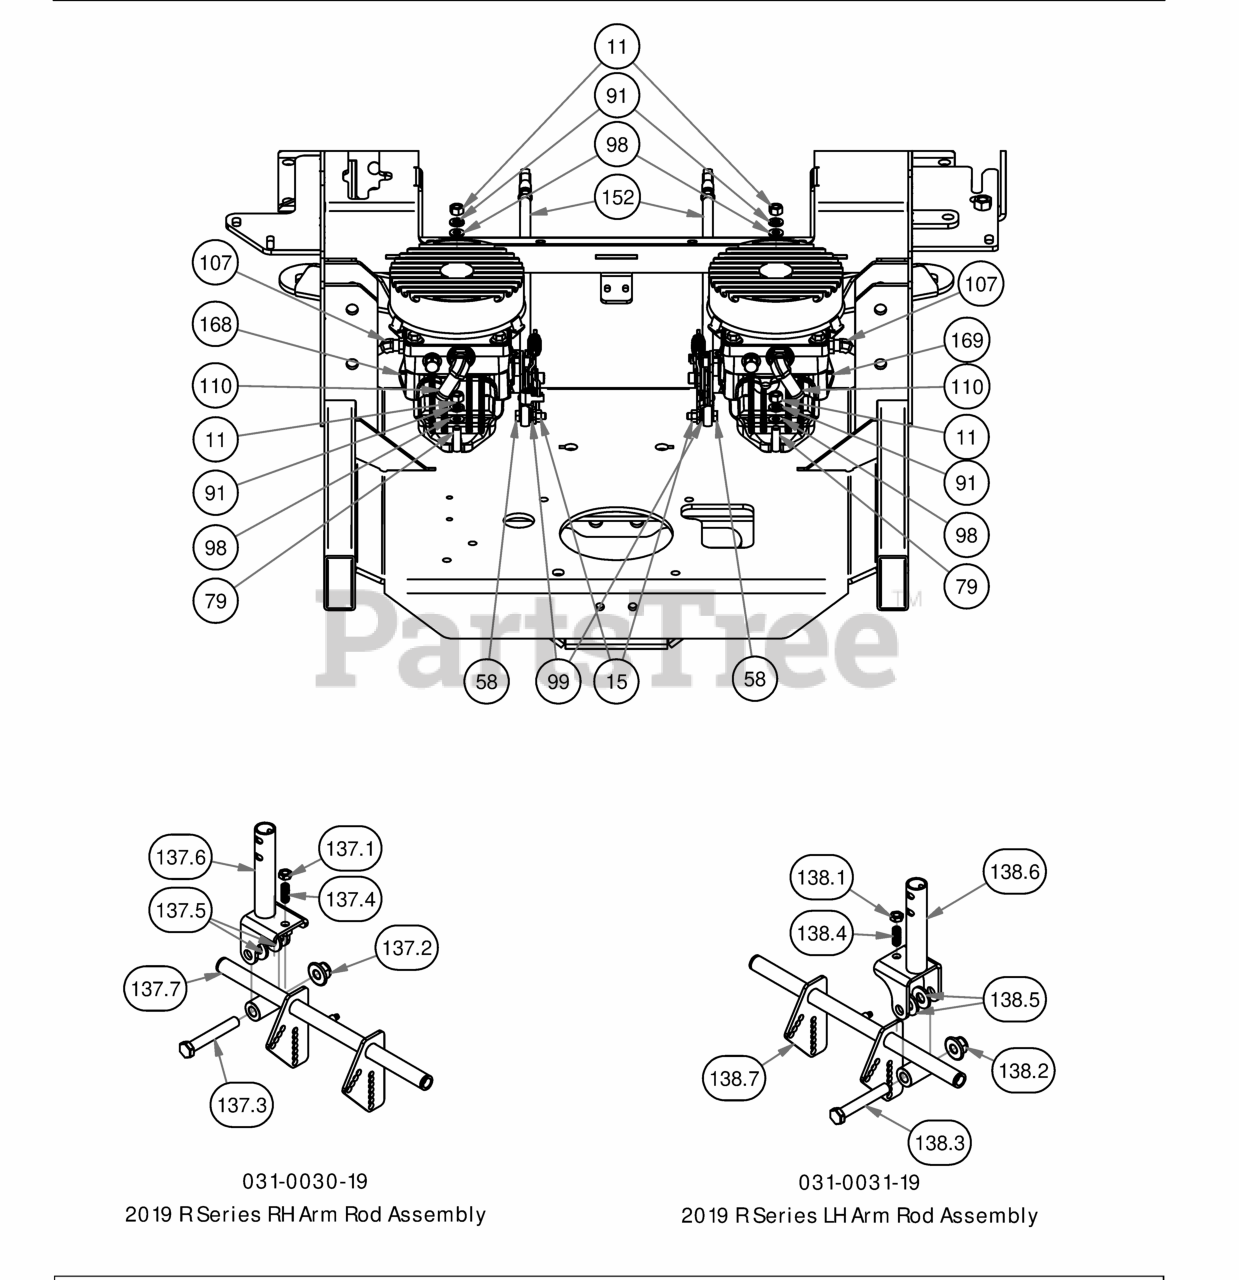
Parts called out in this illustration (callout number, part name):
11	3/8" Hex Nut
58	5/16 x 1 1/4 Hex Bolt
79	3/8 x 1.5" Bolt
91	3/8" Lock Washer
98	5/16" Flat Washer
99	5/16" Lock Washer
107	ZT Fitting, 3/8 x 3/8 45 Degree, 4603-6-6
110	90 Degree Fitting, 1/2 x 3/4, 4601-8-8
137.1	3/8-16 Half Jam Nut
137.2	1/2-13 Nylon Flange Nut
137.3	1/2-13 x 3.25 GR 5 Hex Bolt Zinc
137.4	3/8-16 x 1 Set Socket Set Screw Cup Point
137.5	.505 Nylon Spacer
137.6	Drive Arm Pivot
137.7	2019 Drive Arm Actuator right
138.1	3/8-16 Half Jam Nut
138.2	1/2-13 Nylon Flange Nut
138.3	1/2-13 x 3.25 GR 5 Hex Bolt Zinc
138.4	3/8-16 x 1 Set Socket Set Screw Cup Point
138.5	.505 Nylon Spacer
138.6	Drive Arm Pivot
138.7	2019 Drive Arm Actuator left
152	2019 Outlaw Gen2 XP Push Rod Assembly
168	2019 Rogue/Renegade Left Pump 16cc
169	2019 Rogue/Renegade Right Pump 16cc
